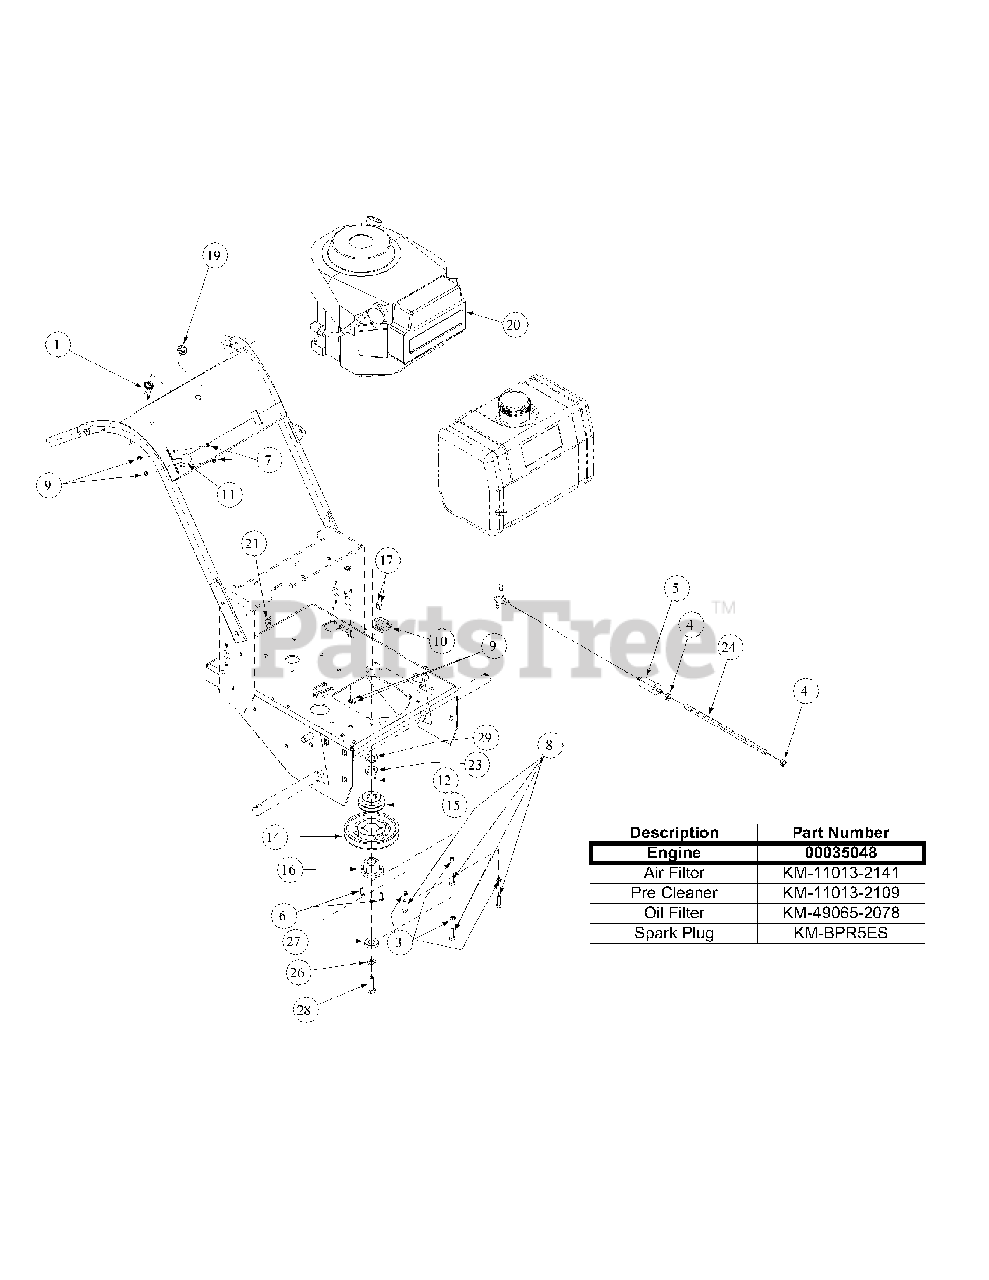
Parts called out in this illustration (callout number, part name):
1	Single Ignition ON/OFF Switch
3	Lock Washer, 5/16
4	Clamp
5	Kohler Fuel Filter
6	Hex Cap Screw, 1/4-20 x 3/4
7	Screw, Hex Washer, 10-32 x 1/2
8	Cap Screw, 1.25 x 30
9	Lock Nut, Nylon Insert, 10-32
10	Delta Switch
11	Control Throttle w/Detent, 39.2
12	Key Stick, 1/4 x 1/4 x 2-3/4
14	Deck Pulley
15	Traction Pulley
17	Machine Screw, 10-32 x 5/8
18	Support Clamp Tubing, 1/2"
19	Nut w/cap, 5/8-32 Ignition
20	14 Hp Kawasaki Engine
21	Support Clamp, 3/8 OD
23	Flat Washer
24	12" Fuel Hose x .25 ID
26	Lock Washer, 7/16
27	Clutch Washer
28	Hex Cap Screw, M10 x 1.5, 30mm, GR10.9
29	Spacer, Engine Pulley
